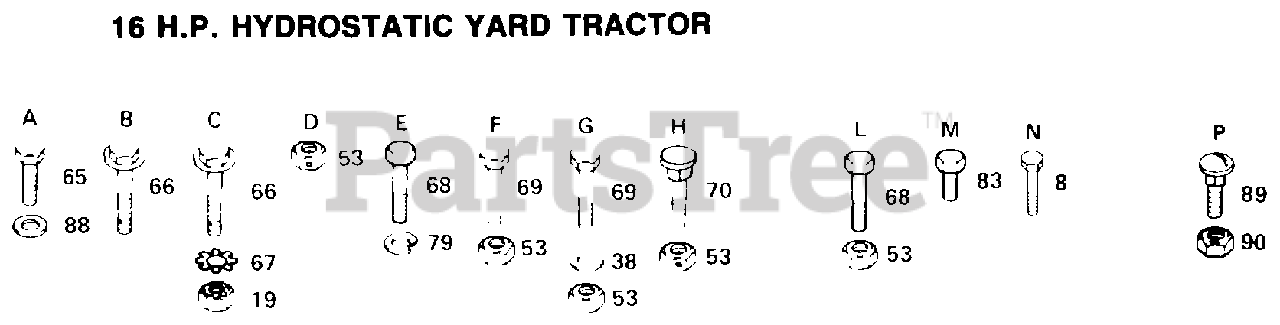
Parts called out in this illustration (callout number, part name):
19	NUT
38	WASHER
65	SCREW
66	SCREW LT
67	LOCKWASHER
69	BOLT
70	BOLT
79	LOCKWASHER
83	SCREW
88	WASHER
89	BOLT
